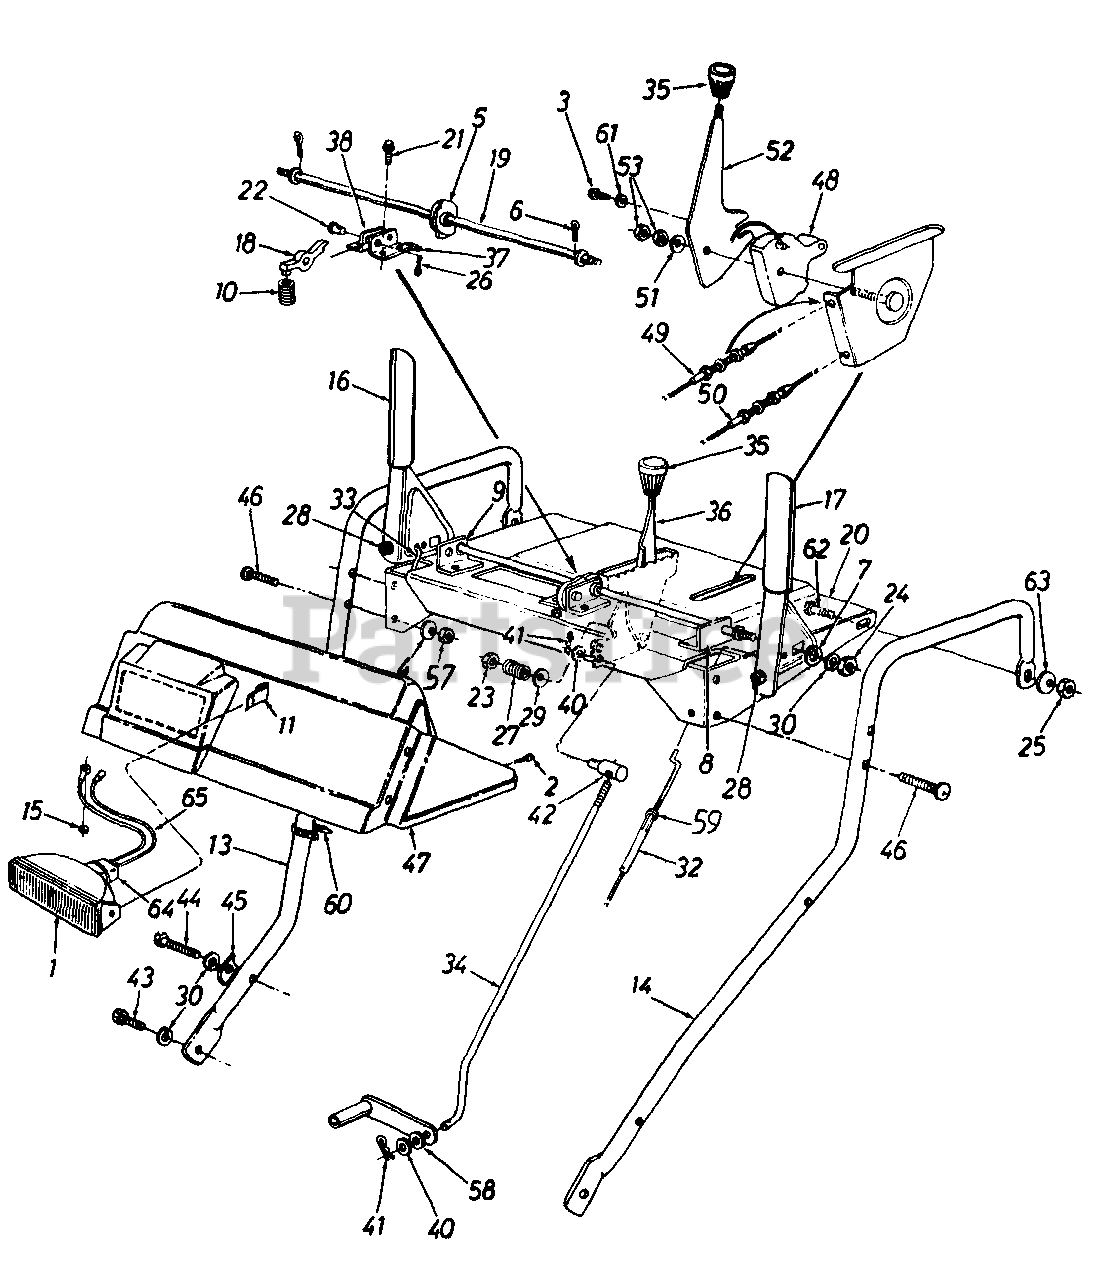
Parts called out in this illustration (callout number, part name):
1	Lamp Housing w/Lens
2	Truss Mach. B-Tap Scr. #10 x .5
3	Hex AB-Tap Scr. 1/4 x .62" Lg.
4	Bell-Wash. .325" I.D. x .88" O.D.
5	Cam Handle Lock
6	Cotter Pin 3/32" Dia. x .75" Lg.
7	Washer (Special) .72" O.D.
10	Compression Spring
11	Retaining Clip
13	Handle - R.H.
16	Engagement Handle - R.H.
17	Engagement Handle - L.H.
18	Pawl Handle Lock
19	Rod Cam
22	Clevis Pin .437" Dia. x .65" Lg.
23	Hex Ins. L-Nut 3/8-24 Thd.
24	Hex Nut 5/16-18 Thd.
25	Hex Nut 1/4-20 Thd.
26	Cotter Pin 3/32" Dia. x 1" Lg.
27	Compression Spring
28	Rubber Bumper
29	Bell-Wash. .38" I.D. x .88" O.D.
30	L-Wash. 5/16" I.D.
32	Auger Clutch Cable
33	Drive Clutch Cable
34	Shift Rod
35	Shift Knob
36	Shift Handle
40	Fl-Wash. .344" I.D. x .62" O.D.
41	Internal Cotter Pin 5/16" Dia.
42	Ferrule
43	Hex Bolt 5/16-18 x .62" Lg. (Special)
44	Hex Bolt 5/16-18 x 1.75" Lg. (Gr. 5)
44	Curved Carr. Bolt 5/16-18 x 1.5" Lg.
45	Handle Tab
48	Cable Guide
49	Chute Control Cable
50	Chute Control Cable w/Clip
51	Bell-Wash. .325" I.D. x .93" O.D.
53	Hex Cent. L-Nut 5/16-18 Thd.
57	Hex Nut 5/16-18 Thd.
58	Spr. Wash. .32" I.D. x .62" O.D.
59	Hex Nut #10-24 Thd.
60	Cable Tie
61	Washer (Special) 1.25" O.D.
62	Hex Bolt 1/4-20 x .85" Lg.
63	Bell-Wash. .265" I.D. x .75" O.D.
64	Bulb
65	Wire Harness
